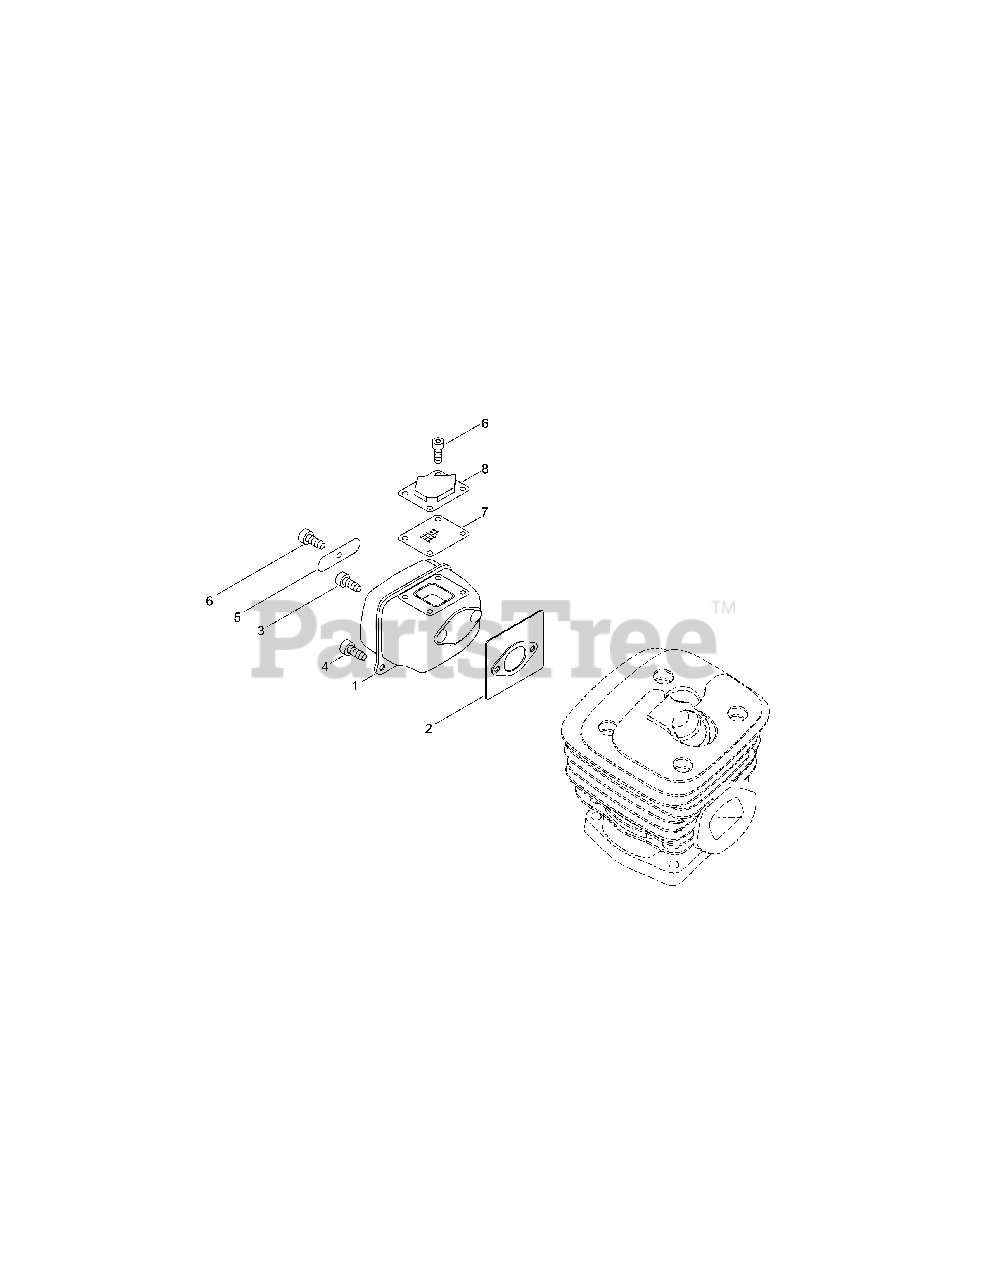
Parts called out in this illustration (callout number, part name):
1	MUFFLER
2	GASKET, EXHAUST
3	BOLT, TORX 5×20
4	BOLT, TORX 5×25
5	PLATE, MUFFLER
6	BOLT, TORX 4×8
7	SCREEN, SPARK ARRESTER
8	GUIDE, EXHAUST
